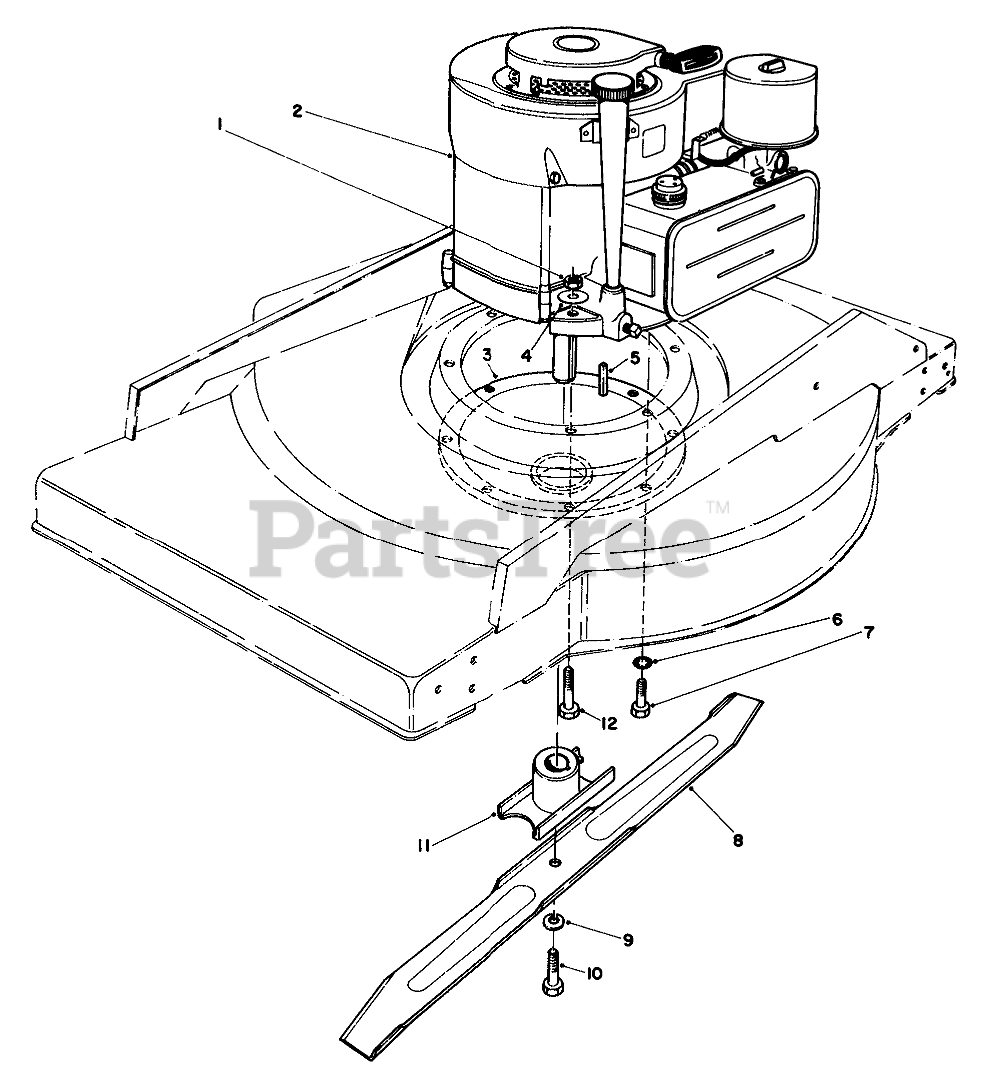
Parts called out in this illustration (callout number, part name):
1	NUT-LOCK, CONE
2	Engine
3	PROTECTOR-CRANKSHAFT
4	WASHER-FLAT
6	WASHER-LOCK, INTERNAL
7	SCREW-HWHTF
8	Blade
9	WASHER-LOCK
10	BLADE SCREW
11	BLADE RETAINER W A
12	SCREW-HH
